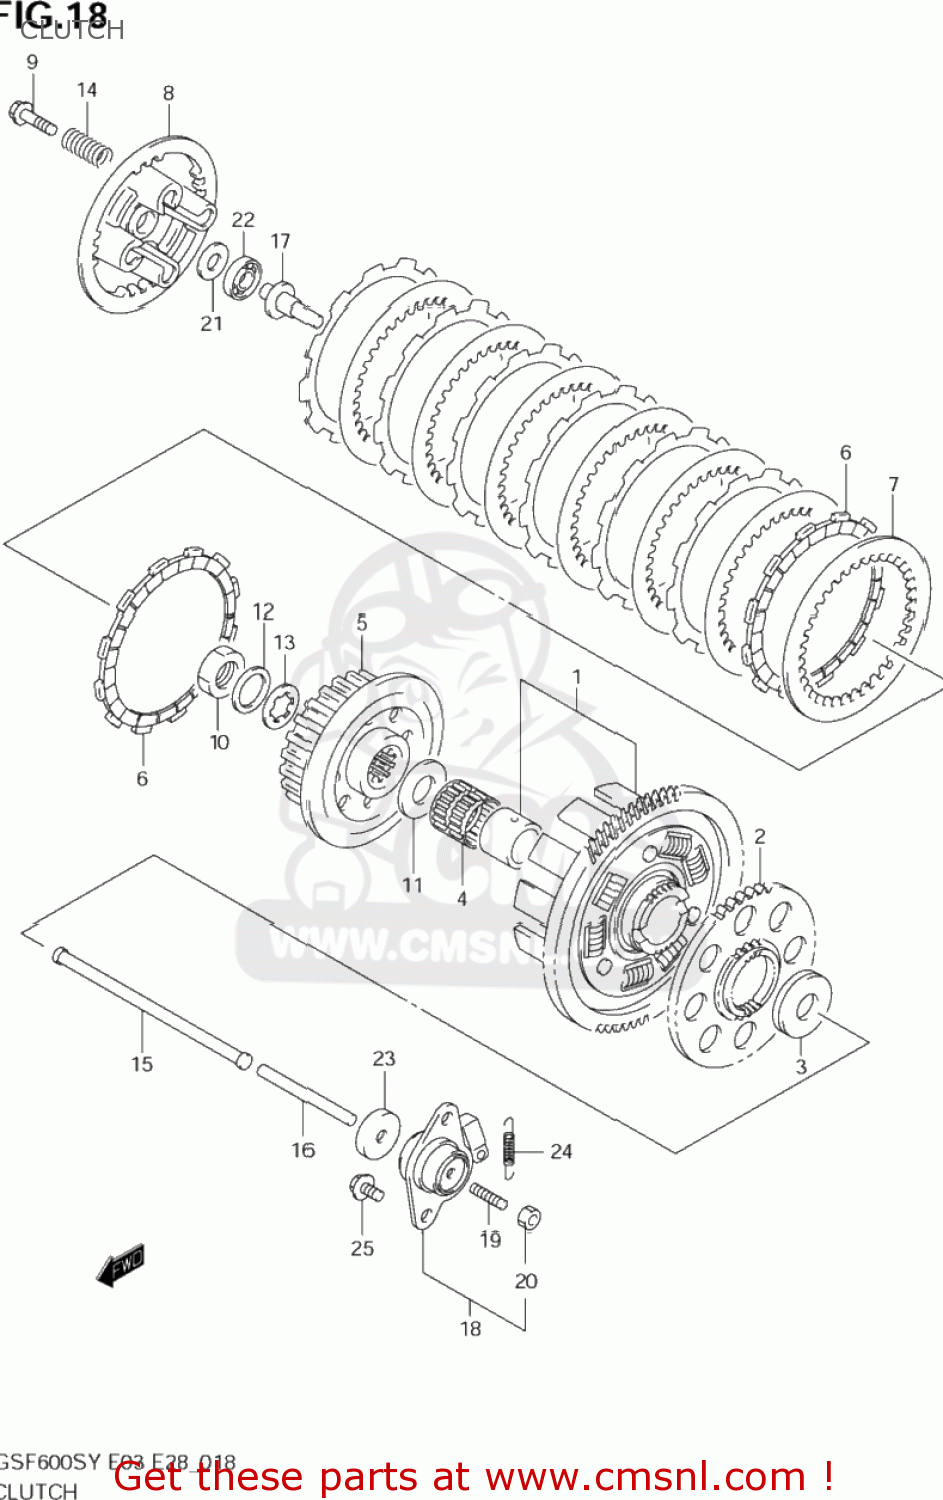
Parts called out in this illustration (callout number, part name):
1	GEAR ASSEMBLY,PRIMARY DRIVE
2	GEAR,GENERATOR DRIVE
3	WASHER(25X54X2.5)
4	BEARING(35X40X35.8)
5	HUB,CLUTCH SLEEVE
6	PLATE,CLUTCH DRIVE (NAS)
7	PLATE,CLUTCH DRIVEN (NAS)
8	DISC,CLUTCH PRESSURE
9	BOLT(6X25)
10	NUT
11	WASHER(25X50X2.5)
12	WASHER
13	SHIM(22X36X1)
14	SPRING
15	ROD,CLUTCH PUSH,R
16	ROD,CLUTCH PUSH,L
17	PIECE,CLUTCH PUSH
18	SCREW ASSY,CLUTCH RELEASE
19	SCREW(6X25)
20	NUT
21	WASHER(15.5X28X1)
22	BEARING(15X28X2)
23	SEAL,OIL(6X34X5.5)
24	SPRING
25	BOLT
